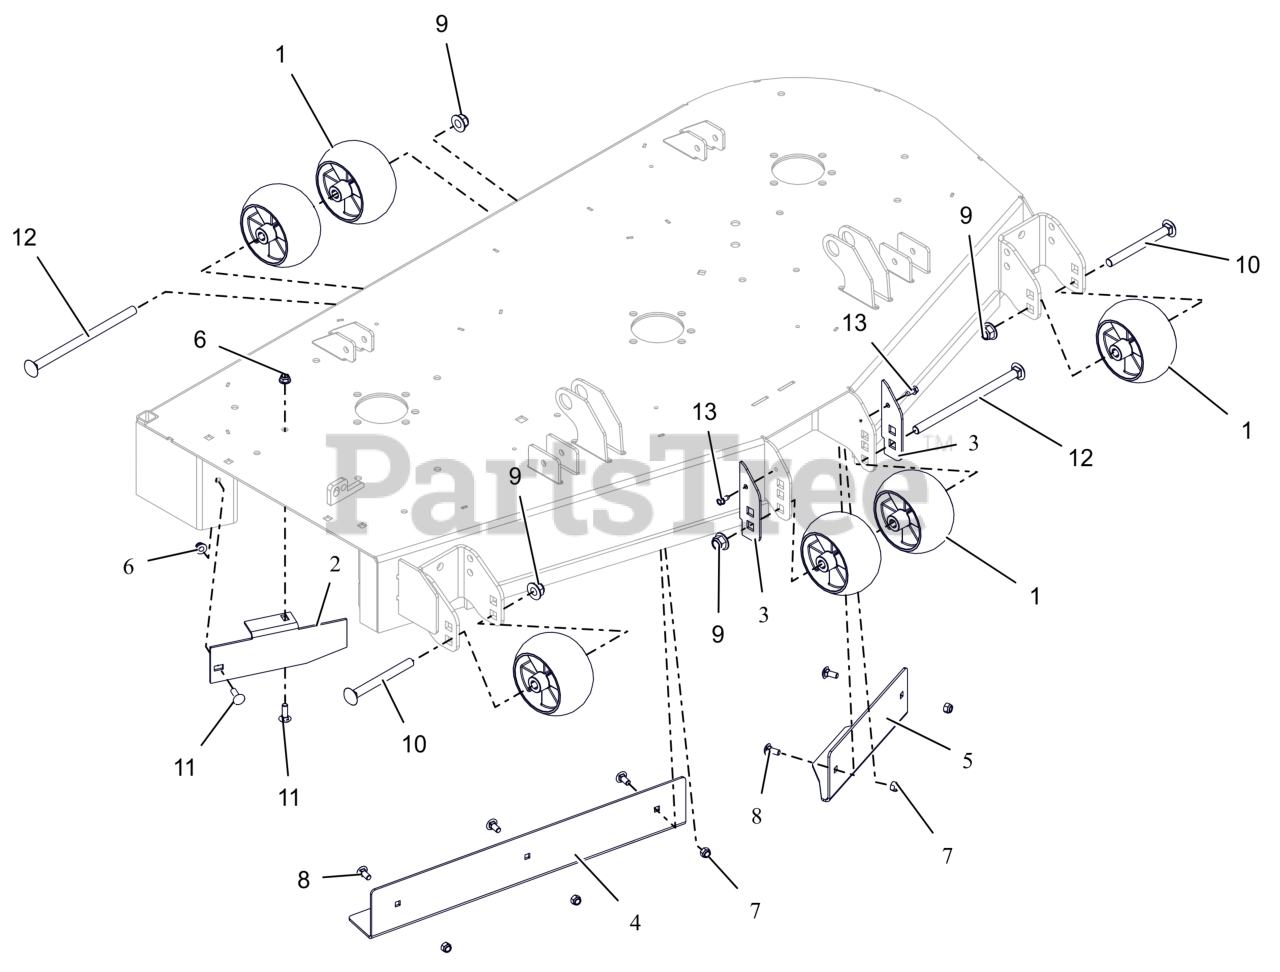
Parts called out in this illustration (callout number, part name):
1	WHEEL, ANTI SCALP - 5X3 CTR W/RIBS
2	BAFFLE, DISCHARGE, 52"
3	PLATE, ANTI SCALP WHEEL EXT.CE
4	BAFFLE, 52" RH VACUUM (ORANGE)
5	BAFFLE, 52" LH VACUUM (ORANGE)
6	NUT,LK-NYL-FLG .31-18 G5ZC120
7	NUT,NYL .31-18 G5 ZCC
8	BLT,RHSN .31-18X.75 G5 ZCC
9	NUT,NYL-FLG .50-13 GF ZCC
10	BLT, RHSN .50-13X5.00 G5 ZCC
11	BLT,RHSN .31-18X1.00 G5 ZCC
12	BTL,RHSN .500-13 X 8.5S G5 ZCC
13	SCR-TAP .25-20X.50 HWH ZCC
